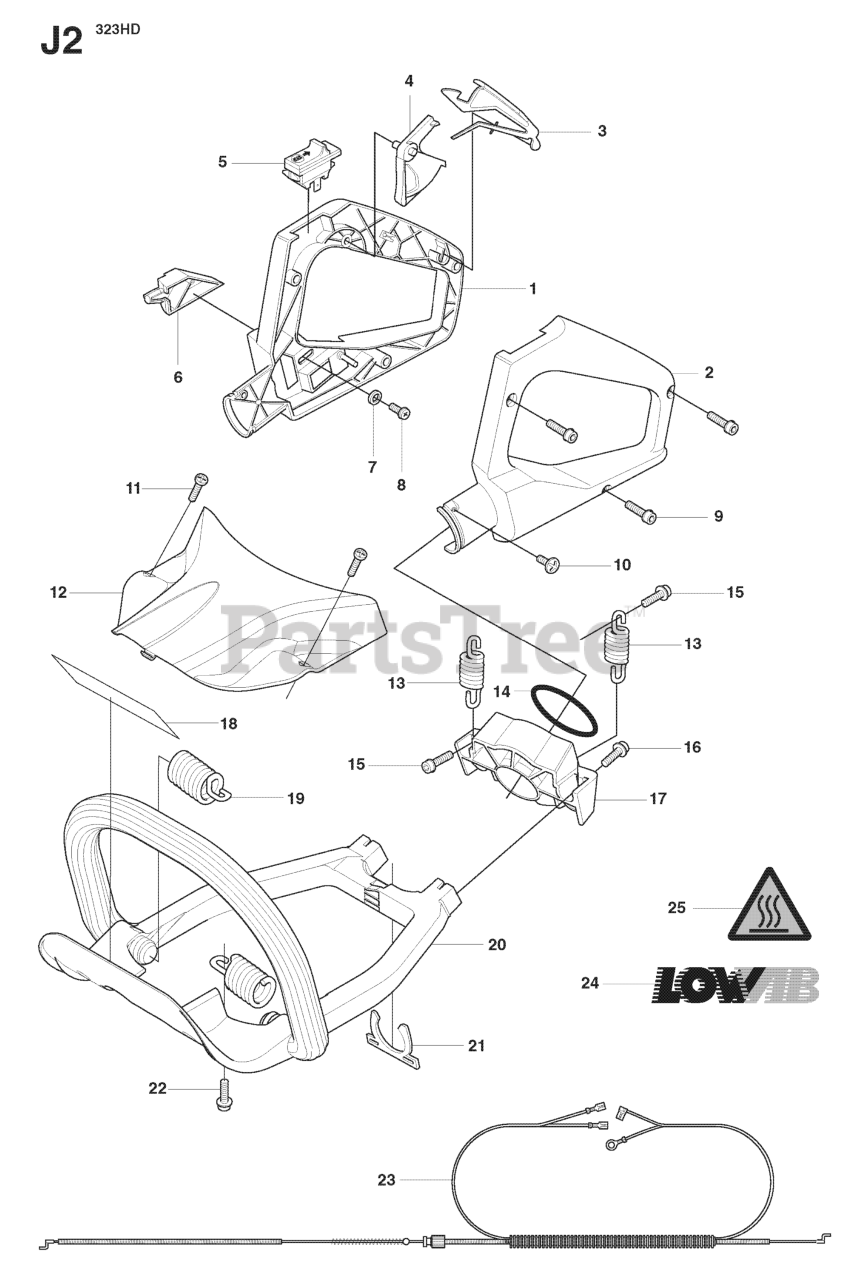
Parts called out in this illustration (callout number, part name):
1	REAR HANDLE COMPLETE
2	HANDLE PART
3	THROTTLE LOCK
4	THROTTLE TRIGGER
5	STOP BUTTON
12	HEAT PROTECTOR EXHAUST PIPE
13	VIBRATION ABSORBER
19	VIBRATION ABSORBER
